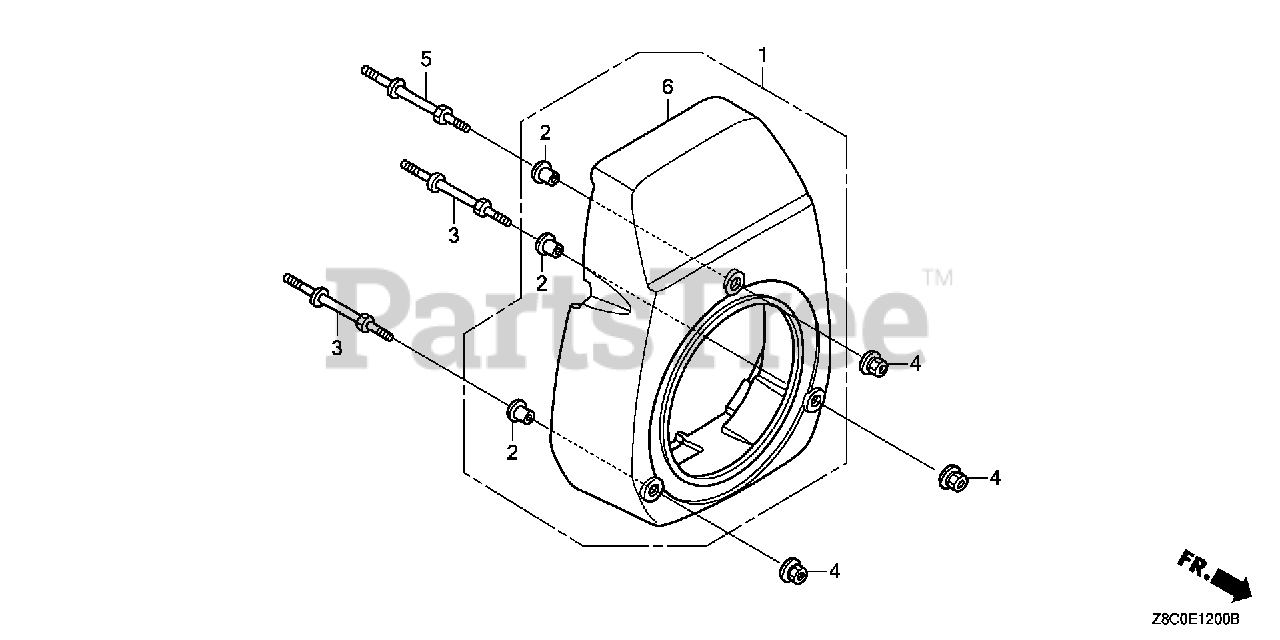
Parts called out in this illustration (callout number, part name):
1	COVER, FAN *NH1* (BLACK)
1	COVER, FAN *R280* (POWER RED)
1	COVER, FAN *R280B* (POWER RED)
2	COLLAR, FAN COVER
3	BOLT, STUD (H=42.5MM)
3	BOLT, STUD (FAN COVER)
4	NUT, FLANGE (6MM)
5	BOLT, STUD (H=42.5MM)
5	BOLT, STUD (H=39.5MM)
5	BOLT, STUD (FAN COVER)
6	COVER, FAN *NH1* (BLACK)
6	COVER, FAN *R280* (POWER RED)
6	COVER, FAN *R280B* (POWER RED)
